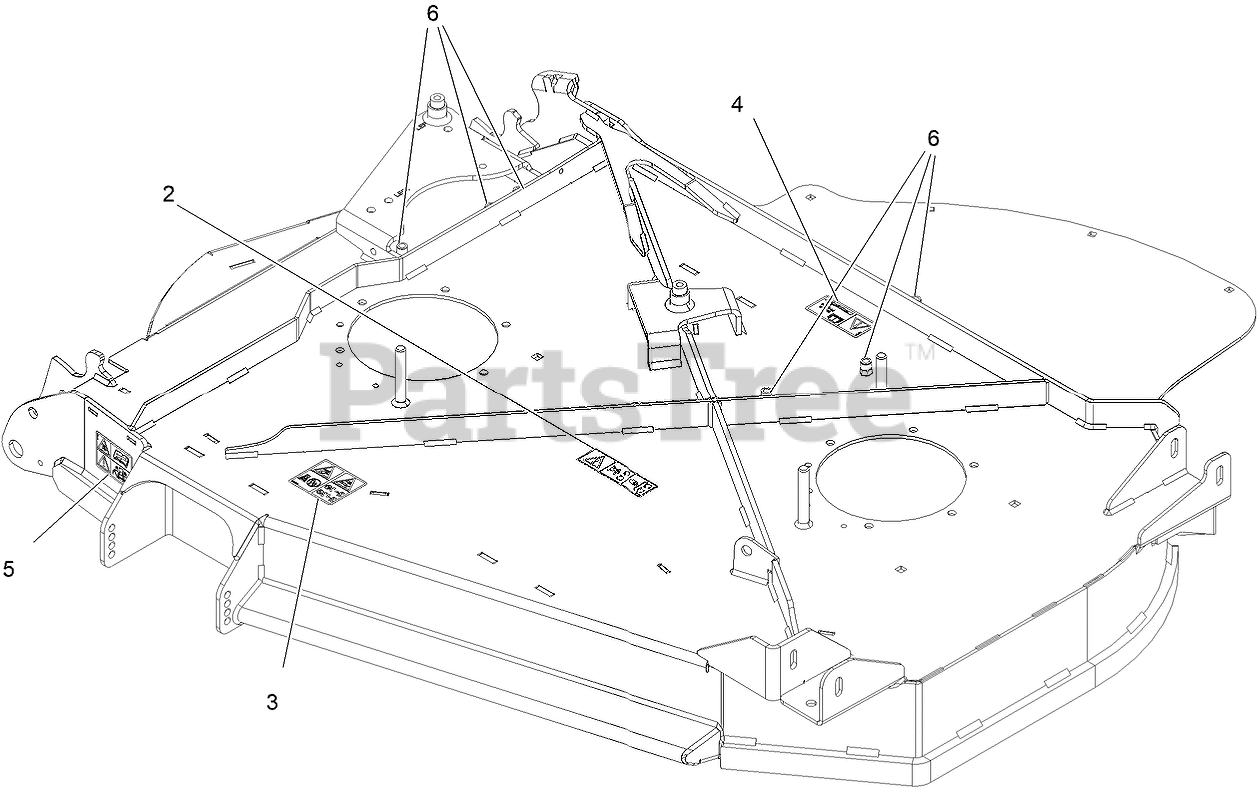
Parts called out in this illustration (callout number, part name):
2	DECAL-COVER, MISSING
3	DECAL-DANGER, THROWN OBJECT
4	DECAL-TORQUE, BOLT
5	DECAL-WARNING, PINCH POIN
6	NUT-CLINCH,HEX
